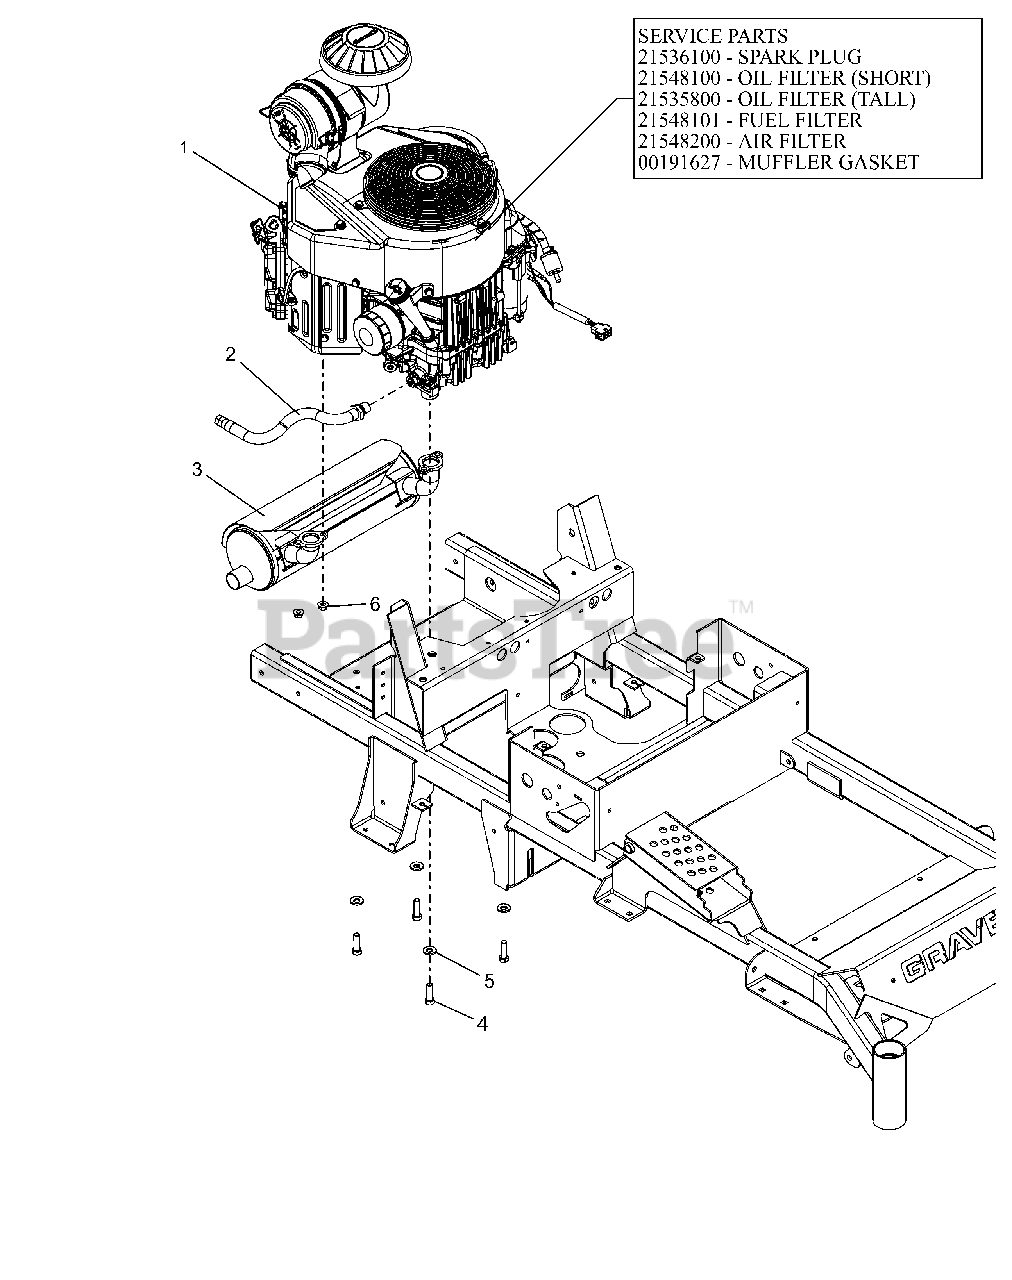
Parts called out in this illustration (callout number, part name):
1	ENGINE, KAWASAKI FX600
1	PLUG, SPARK
1	OIL FILTER, KAWASAKI FR
1	FILTER,OIL - KAW
1	FUEL FILTER-KAWASAKI FR
1	AIR FILTER
1	GASKET, MUFFLER S/O
2	HOSE, OIL DRAIN
3	MUFFLER, ACTIVE EXHAUST
4	BLT, HEX .38-16X1.25 G5 ZCC NT
5	WASHER, 3/8" SPRING DISC
6	NUT-LK-TOP-FLG M8 ZCC
